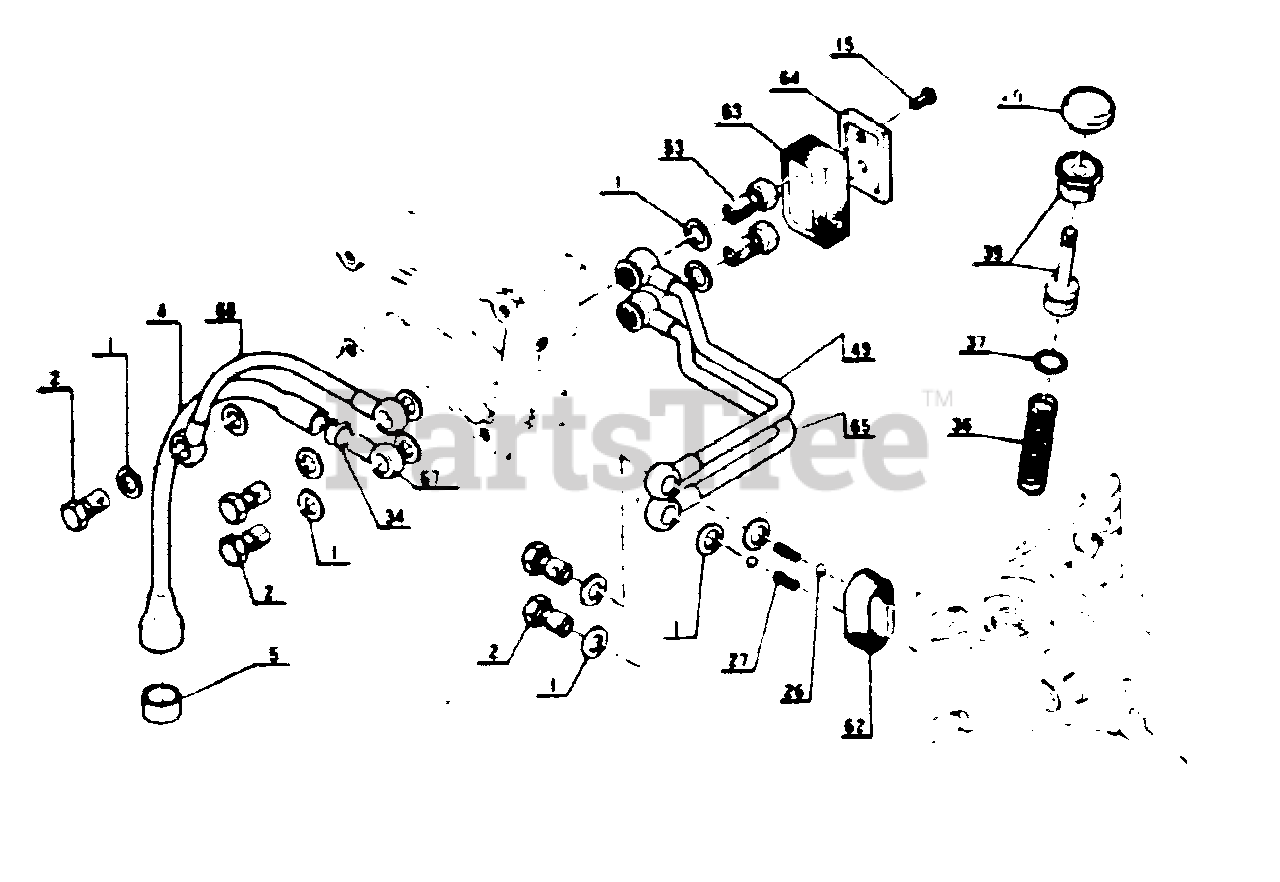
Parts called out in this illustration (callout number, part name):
1	GASKET
2	HOLDING BOLT
4	PIPE, OIL - INNER
5	FILTER, OIL
15	SCREW - 3×6
26	VALVE, BALL
27	SPRING, VALVE
34	CLIP
36	SPRING, OIL PUMP
37	O-RING
39	PISTON, OIL PUMP
40	PUSH BUTTON
49	PIPE, OIL
53	HOLDING BOLT
63	SEAL, DUST
64	SEAL, DUST
65	PIPE, OIL
67	CONNECTOR
68	PIPE, OIL
